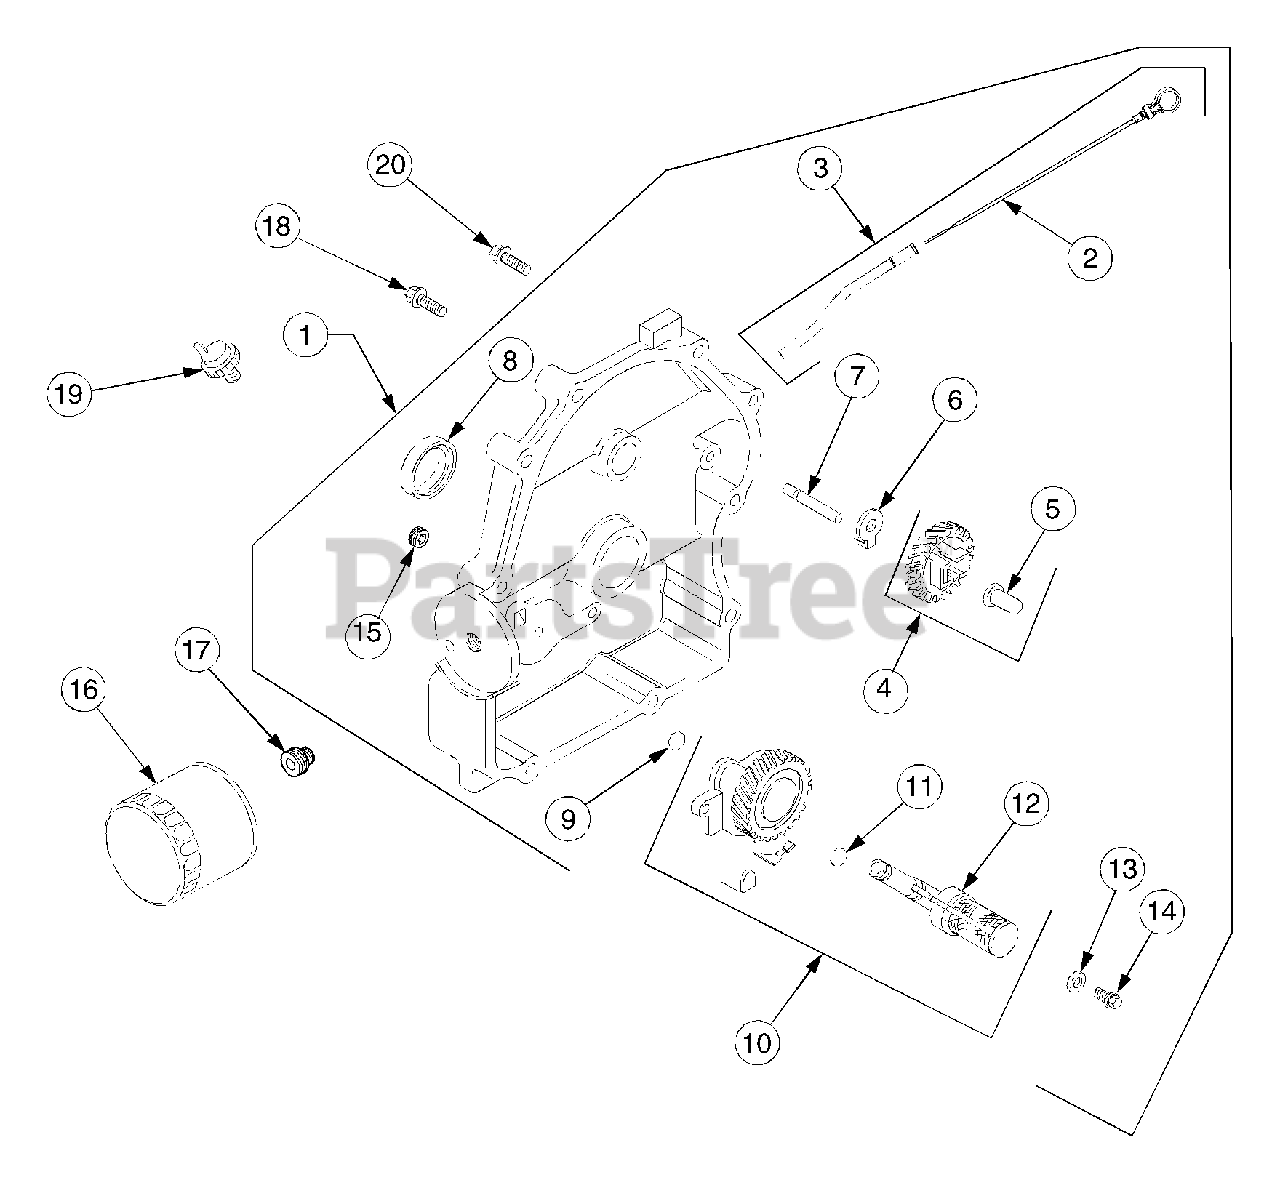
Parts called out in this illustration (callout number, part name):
1	Plate, Closure Assembly
3	Tube, Dipstick
4	Kit, Governor Gear
5	Pin, Governor Regulating
7	Shaft, Governor Gear
8	Seal, Oil (PTO End)
10	Oil Pump Assembly
11	O-Ring, Oil Pick-Up
12	Pick-Up, Oil
13	Washer, Plain
14	Screw, Hex Flange M6 x 1 x 25
15	Plug, Pipe 1/8"
16	Filter, Oil
17	Nipple, Oil Filter
18	Screw, Hex Flange M8 x 1.25 x 45
19	Switch, Pressure
20	Screw, Hex Flange M8 x 1.25 x 45
